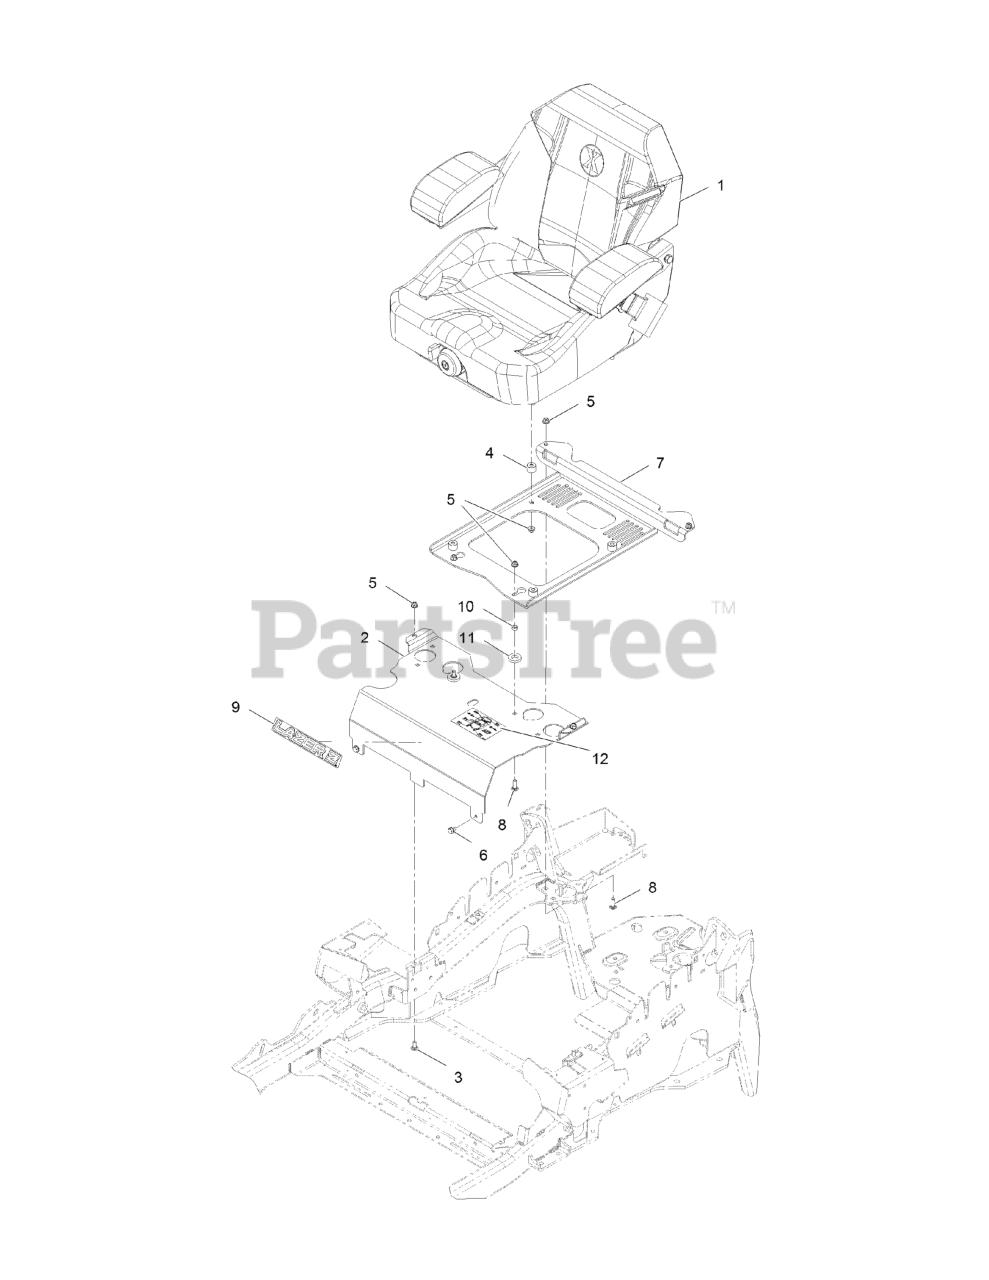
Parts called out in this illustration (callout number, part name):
1	KIT-SUSPENSION SEAT
2	Panel-Front, Seat Mount
3	SCREW-CARR
5	NUT-HF, NI
7	PLATE-SUPPORT, SEAT
8	SCREW-CARR
9	DECAL, LAZER MODEL
10	NUT-HEX
12	DECAL-SERVICE AID
